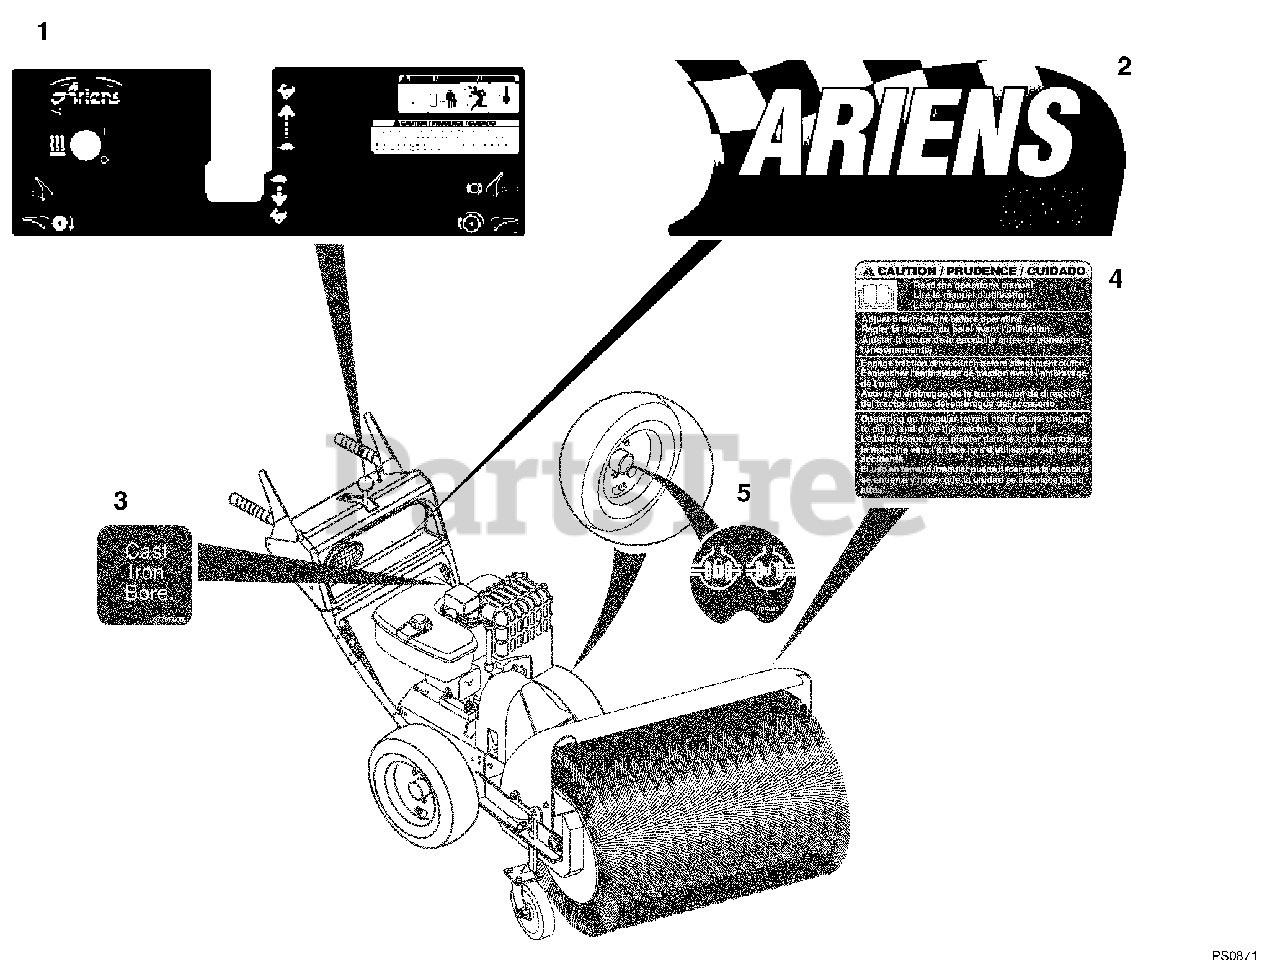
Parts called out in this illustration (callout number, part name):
1	DECAL, CONTROL - 936
2	DECAL, FRONT PANEL - 936
3	DECAL - CAST IRON BORE
4	DECAL, DANGER - POWER BRUSH
5	DIFFERENTIAL LOCK DECAL
